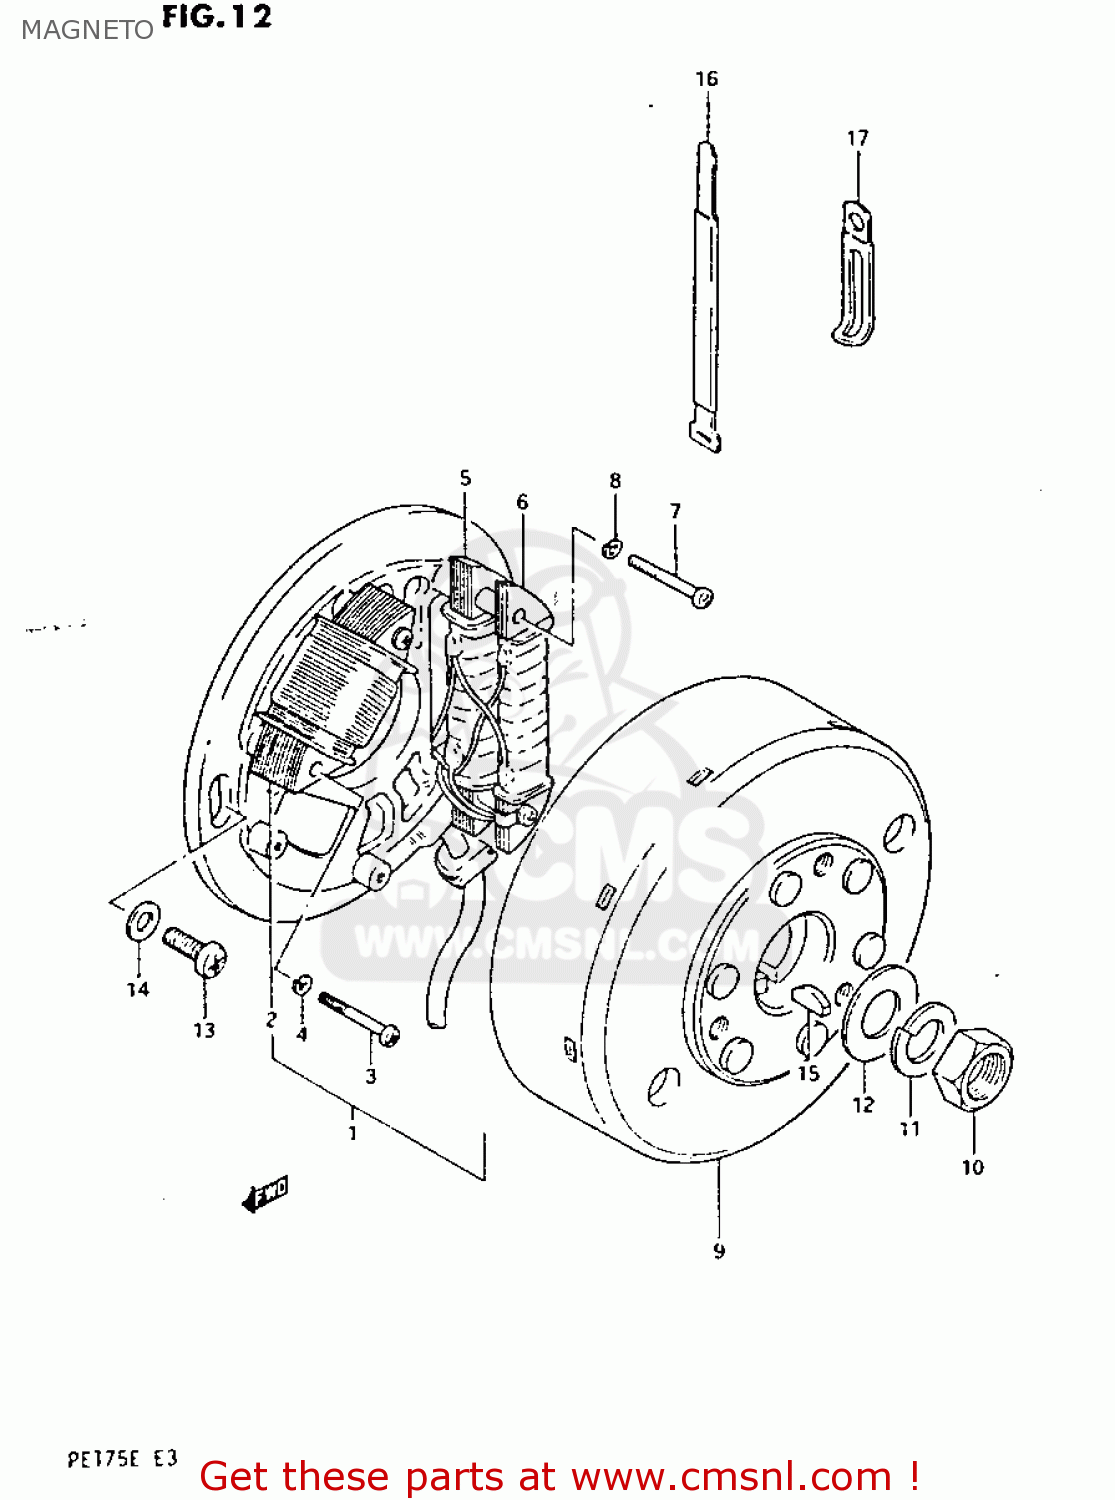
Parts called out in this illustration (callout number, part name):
1	STATOR ASSEMBLY
2	COIL,LIGHTING
3	SCREW
4	WASHER,LOCK 4M
5	COIL
6	COIL,PRIMARY
7	SCREW
8	WASHER,LOCK 4M
9	ROTOR ASSEMBLY
10	NUT (10MM)
11	WASHER,LOCK,10
12	WASHER
13	SCREW
14	WASHER
15	KEY 4MM
16	CLAMP L:110
17	CLAMP
